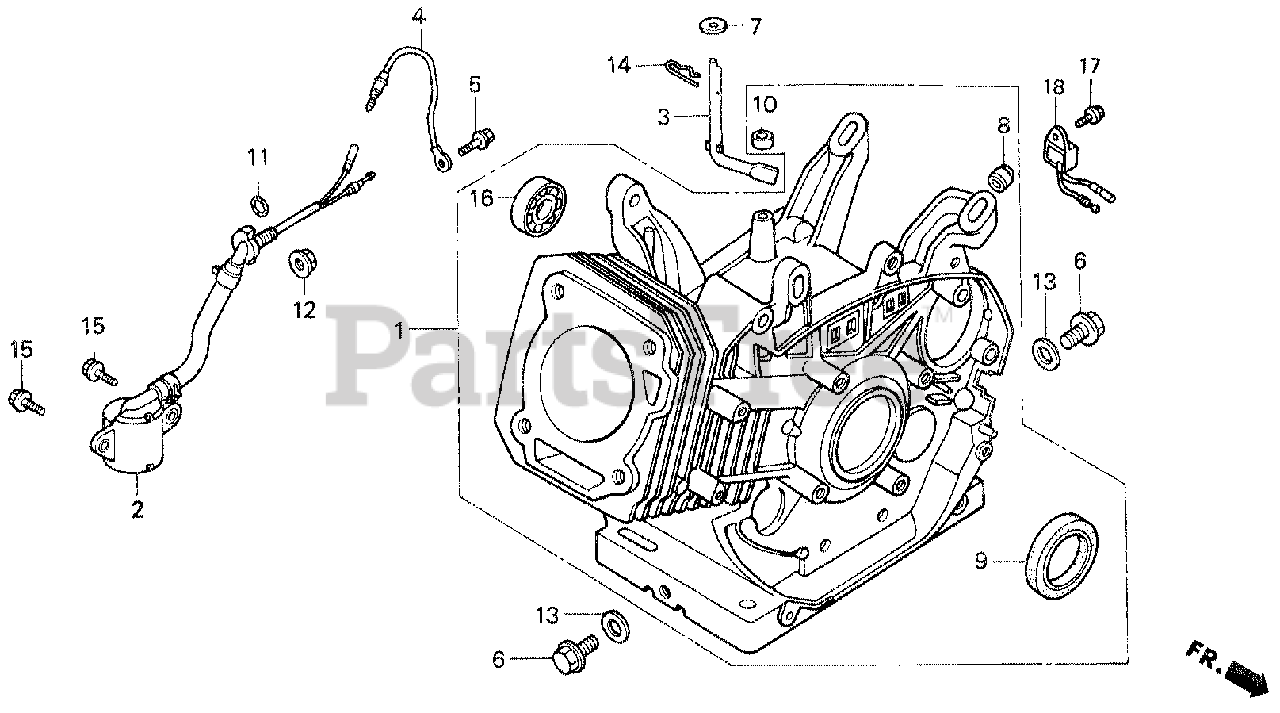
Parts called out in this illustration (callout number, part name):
1	CYLINDER ASSY. (ALERT)
2	SWITCH ASSY., OIL LEVEL
3	SHAFT, GOVERNOR ARM
4	SUB-HARNESS
5	BOLT, FLANGE (6X12) (CT200)
6	BOLT, DRAIN PLUG
7	WASHER (8.2X17X0.8)
9	OIL SEAL (35X52X8)
10	OIL SEAL (8X14X5)
11	O-RING (13.5X1.5) (ARAI)
12	NUT, FLANGE (10MM)
13	WASHER, DRAIN PLUG (12MM)
14	PIN, LOCK (8MM)
14	PIN, LOCK (10MM)
15	BOLT, FLANGE (6X12)
16	BEARING, RADIAL BALL (6202)
